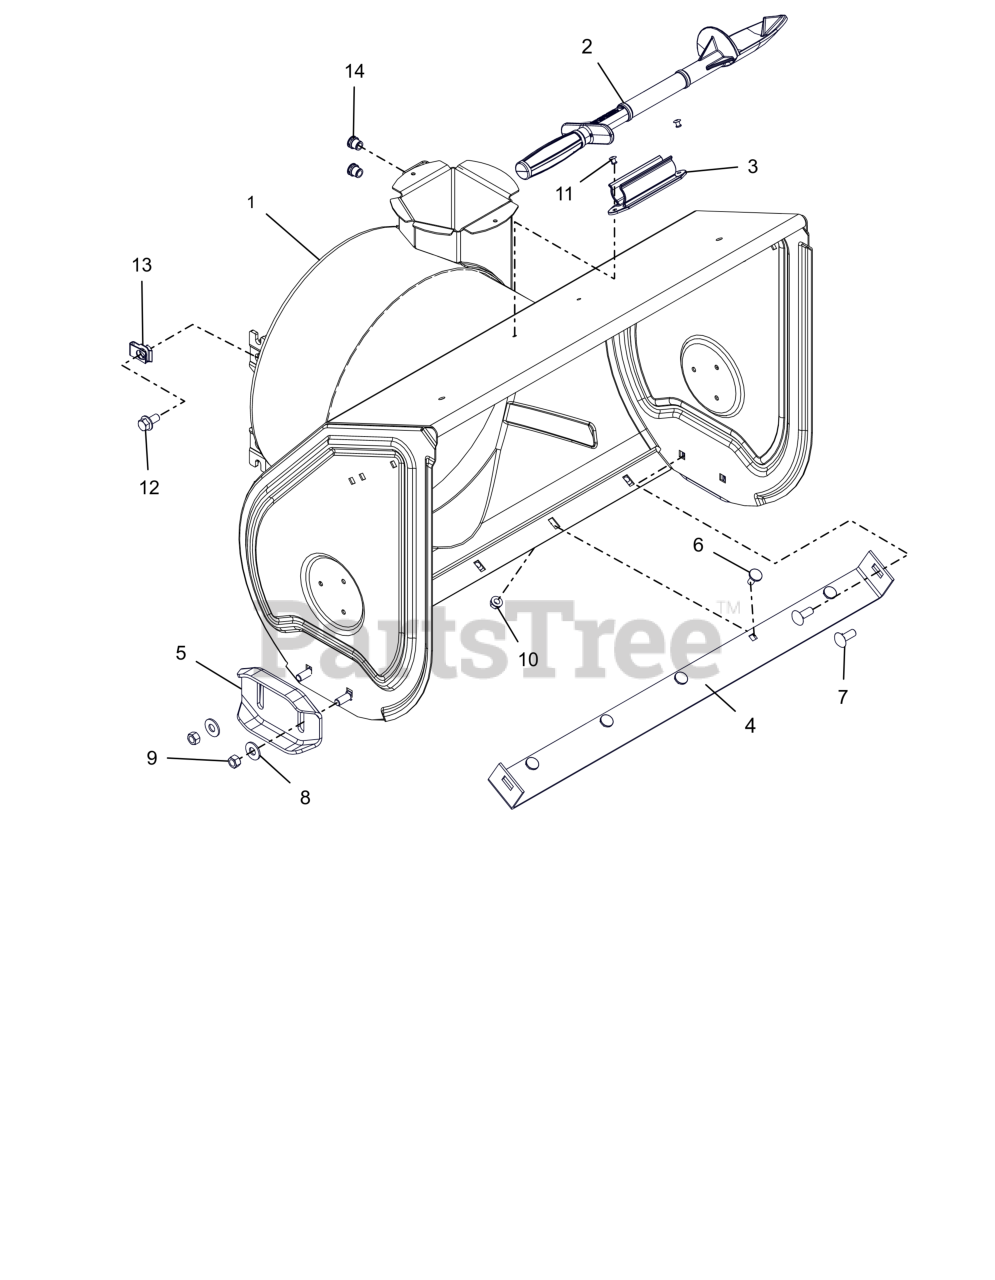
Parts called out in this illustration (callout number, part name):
1	BLOWER HOUSING W/DECAL 28"
2	DEVICE, SNOW CLEAN OUT
3	MOUNT, SNOW CLEAN OUT
4	BLADE, SCRAPER - 28"
5	SKID SHOE, REVERSIBLE - ORANGE
6	BOLT, MODIFIED HEAD CARRIAGE
7	BLT,RHSSN .38-16X1.00 G5 ZCC
8	WSHR,FLT .438X1.00X.083 ZCC
9	NUT-LK-CTR .38-16 ZC120
10	NUT-LK-TOP-FLG .312-18 GF ZCC
11	RVT, POP .1875 ZCC
13	NUT-RTNR .375-16X.37
14	NUT,THD,INSERT .38-16 ZC120
